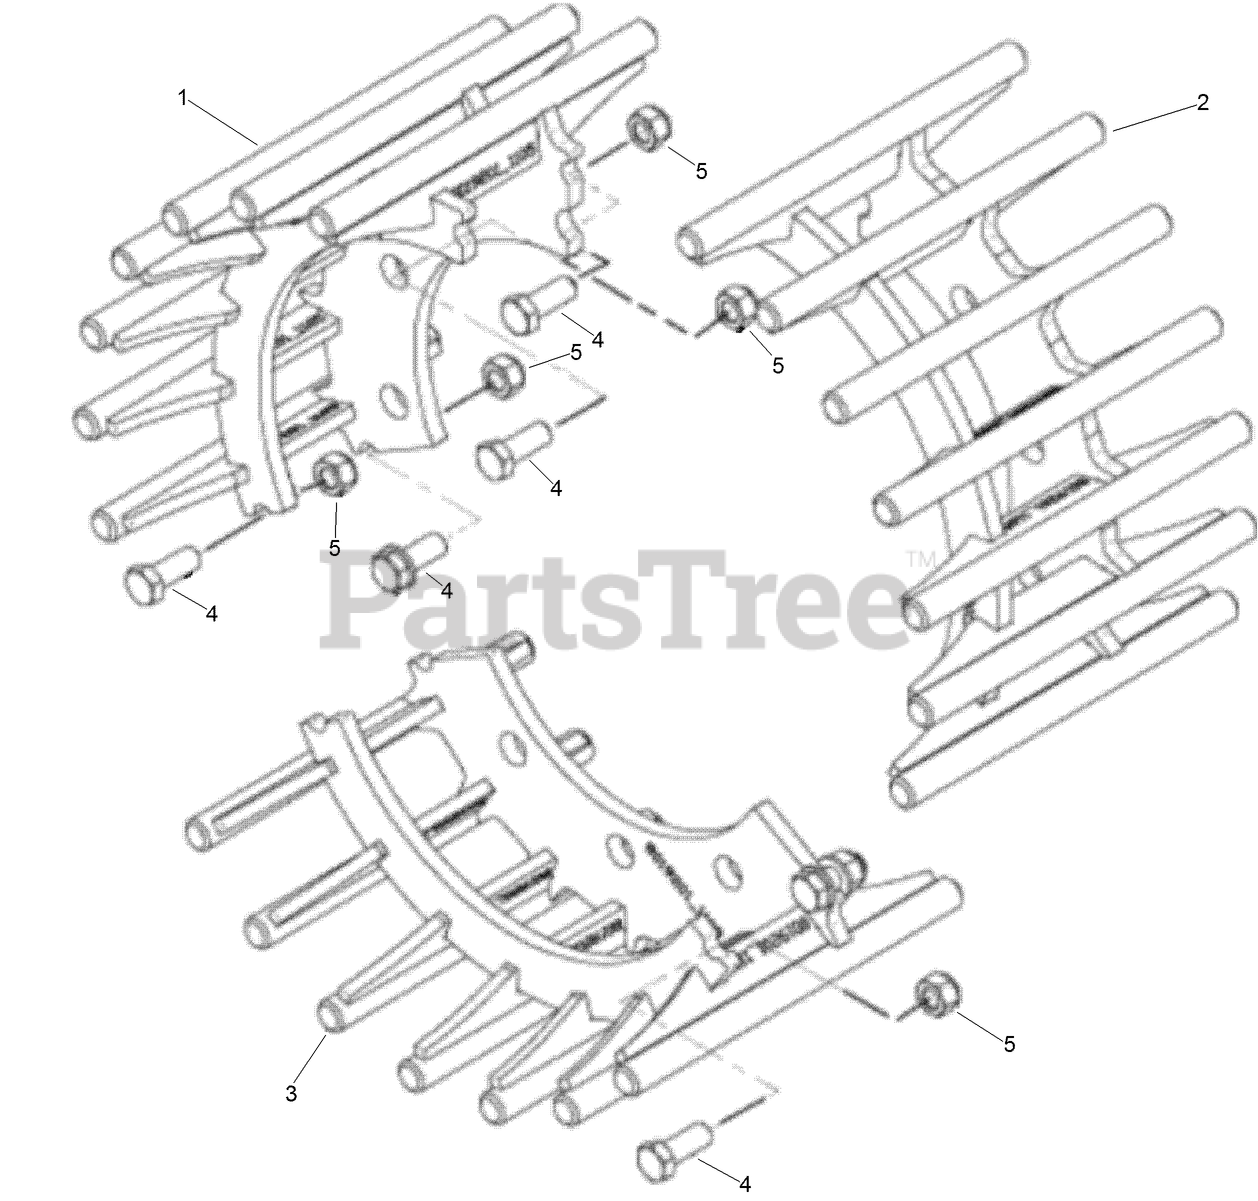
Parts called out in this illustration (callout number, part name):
1	SPROCKET - Third, 7 Teeth
2	SPROCKET - Third, 7 Teeth
3	SPROCKET - Third, 7 Teeth
4	SCREW-HHF
5	NUT-HHF
